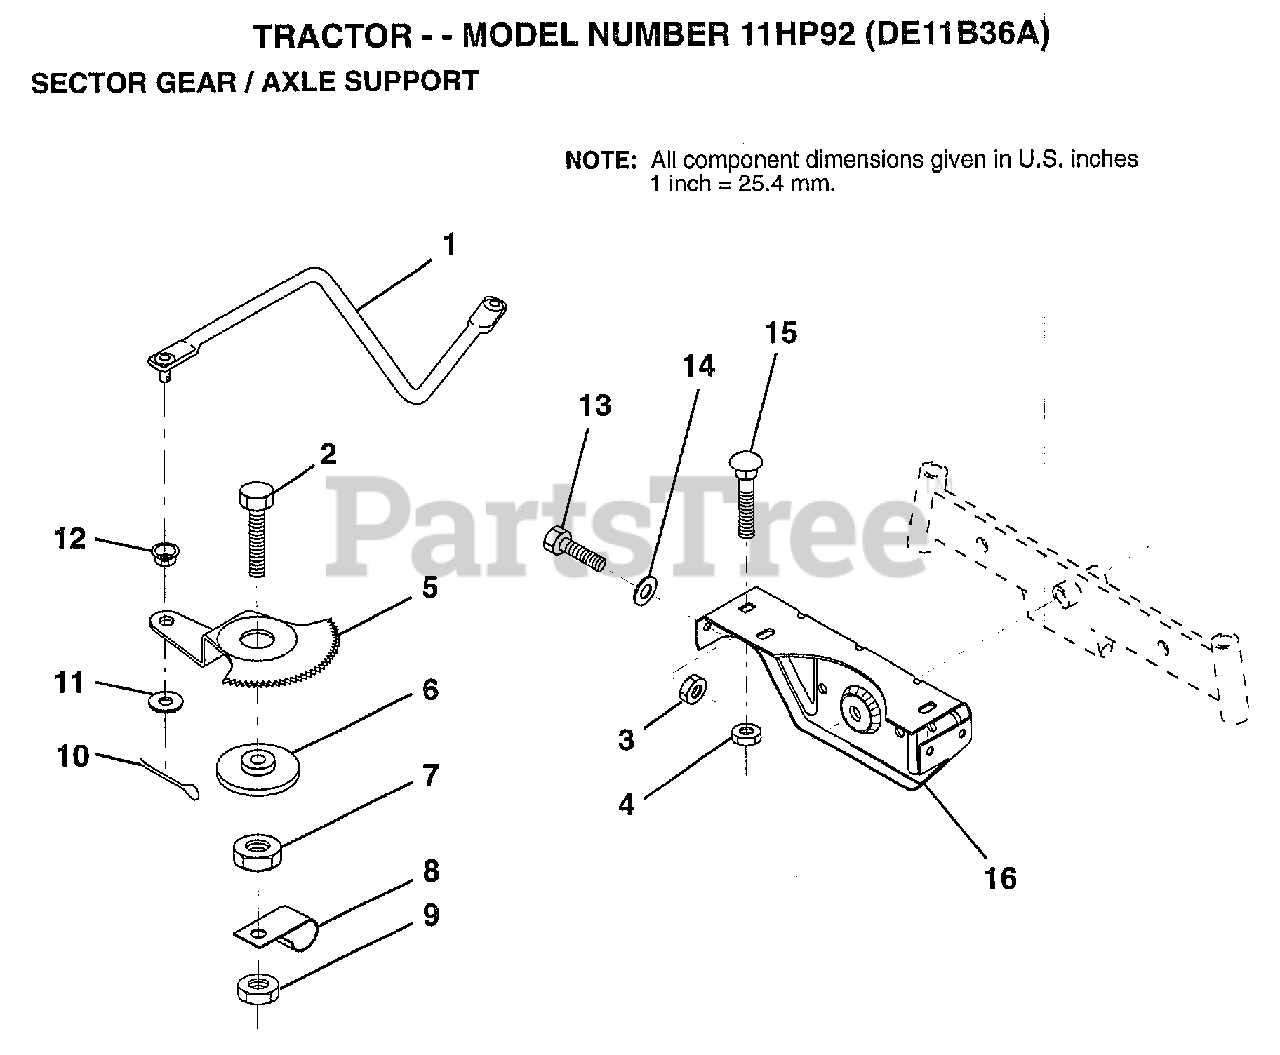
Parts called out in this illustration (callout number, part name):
1	DRAG LINK
2	"BOLT,HEX"
5	GEAR SECTOR
6	BUSHING
7	NUT
8	CLIP INSULATOR
9	NUT LTV
10	COTTER PIN
11	WASHER
12	BUSHING.DRAGLINK
13	BOLT
14	WASHER
15	BOLT
16	SUPT AXLE FRONT
